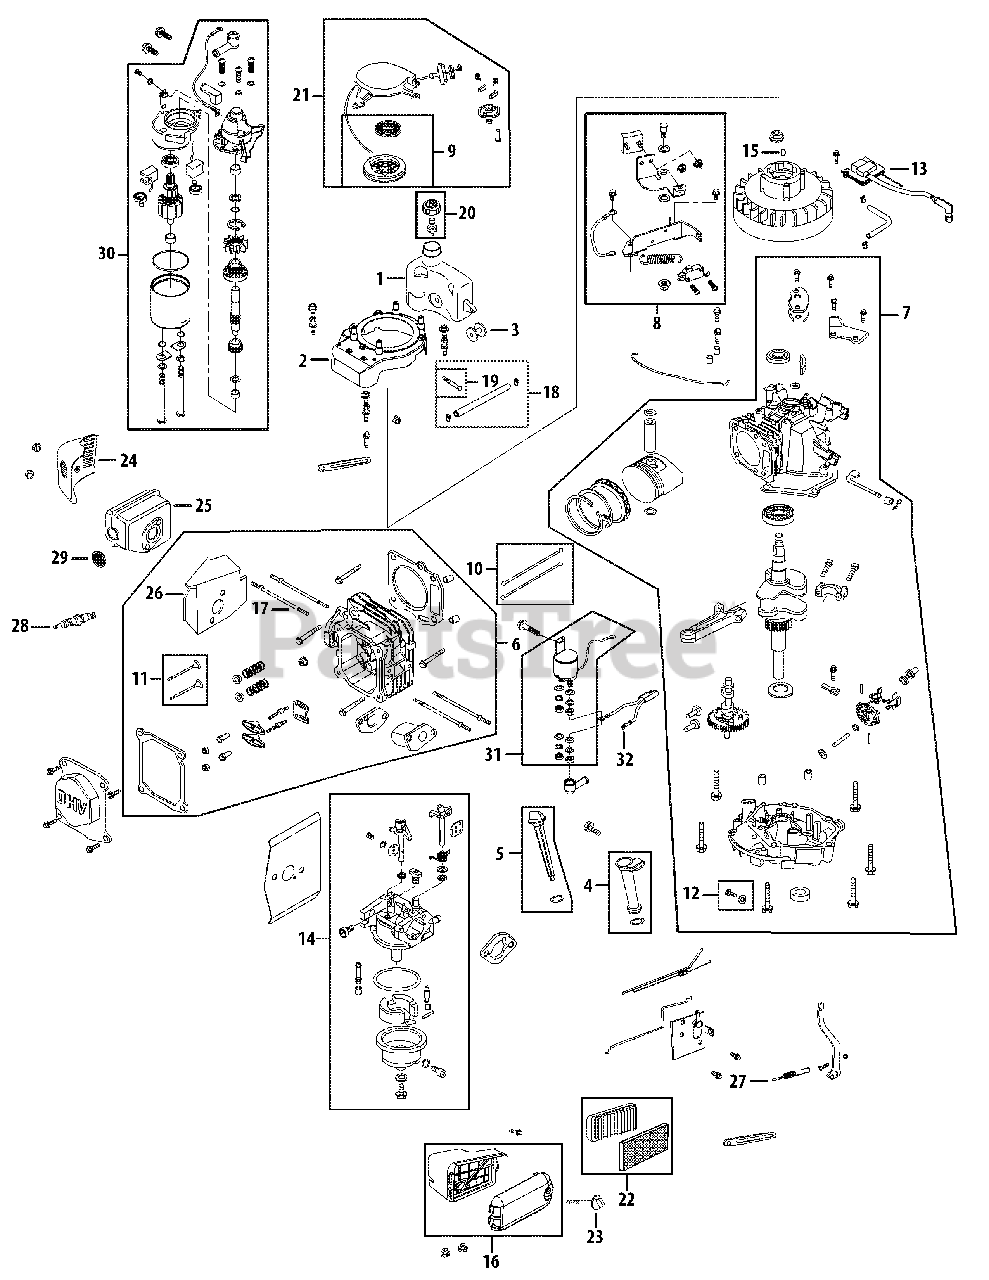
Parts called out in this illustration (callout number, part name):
1	Fuel Tank
2	Flywheel Shroud
3	Rubber Fuel Tank Mounting Washer
4	Oil Filler Tube Assembly
5	Dipstick Assembly
6	Cylinder Head Complete
7	Short Block Assembly
8	Stop Switch and Brake Assembly
9	Recoil Spring and Pulley Assembly
10	Push Rod Kit
11	Valve Kit
12	Oil Drain Plug and Washer Assembly
13	Ignition Coil
14	Carburetor Assembly
15	Flywheel Key
16	Air Cleaner Housing Assembly Complete
17	Muffler Stud Assembly
18	Fuel Line Kit
19	Fuel Filter
20	Fuel Cap Assembly
21	Recoil Starter Assembly
22	Air Cleaner Kit
23	Air Cleaner Thumb Screw
24	Muffler Guard
25	Muffler
26	Muffler Gasket /Heat Shield
27	Governor Return Spring
28	Spark Plug
29	Spark Arrestor
30	Electric Starter
31	Relay Assembly
32	Relay Harness Connector
